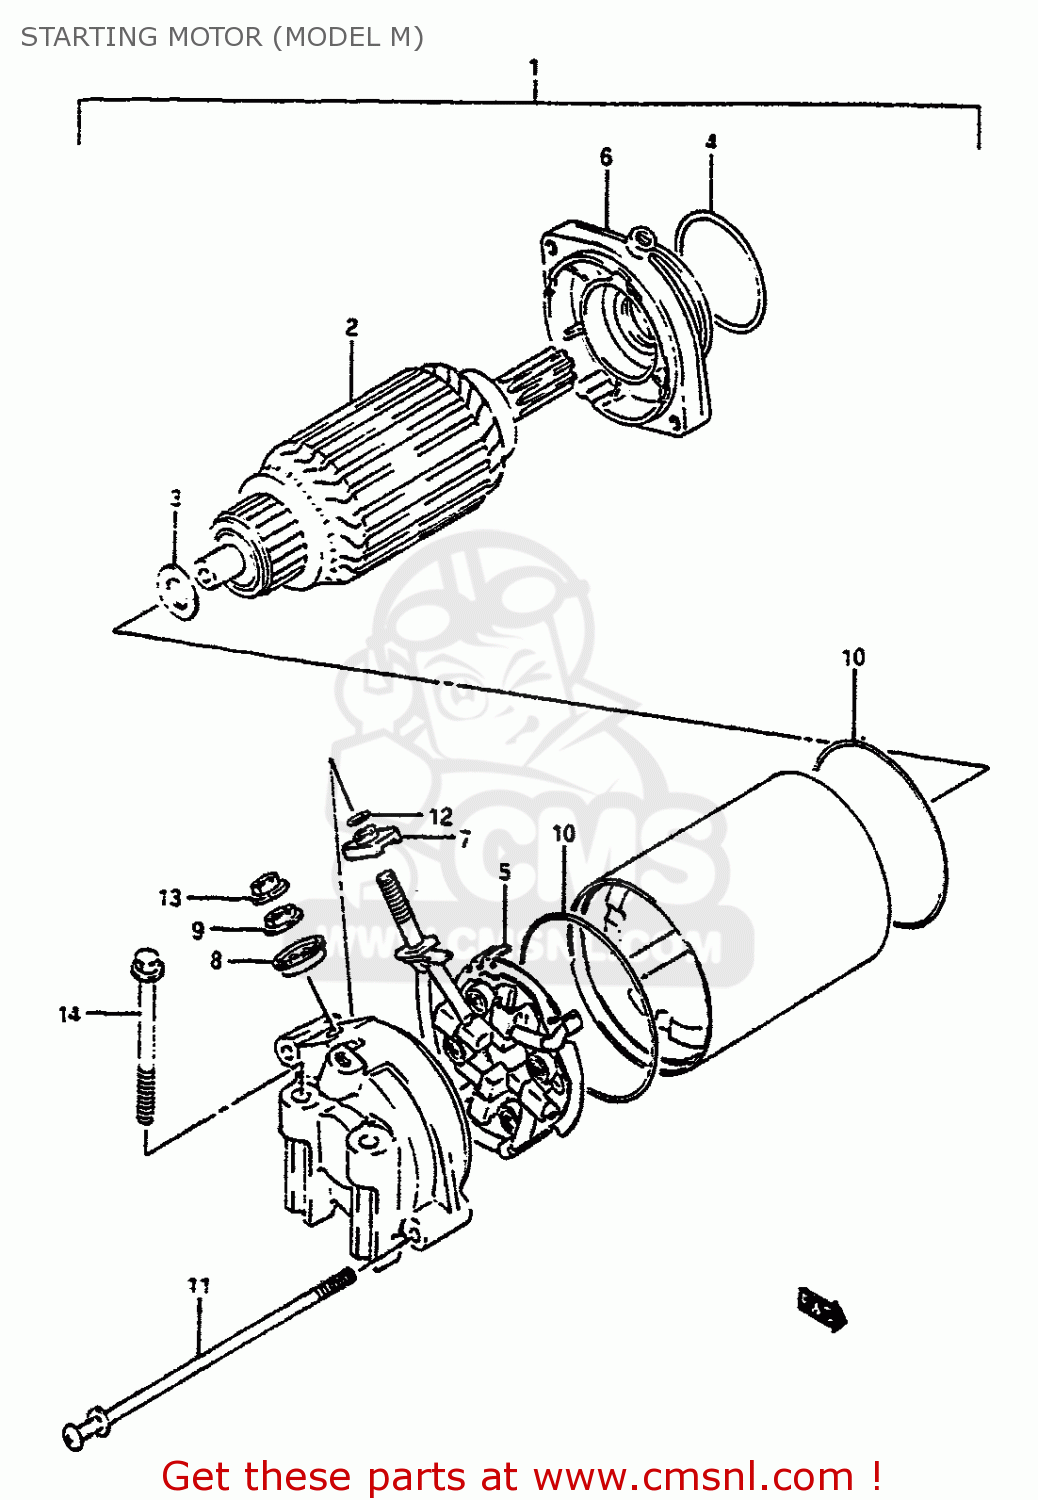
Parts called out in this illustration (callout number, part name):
1	MOTOR ASSEMBLY,STARTING
2	ARMATURE
3	SHIM,ARMATURE
4	O RING
5	HOLDER SET,BRUSH
6	BRACKET SET
7	BUSHING
8	BUSHING
9	NUT
10	BOLT
11	NUT
12	O RING
13	NUT
14	BOLT
15	NUT
15A	NUT
16	WASHER,LOCK
17	BOLT
